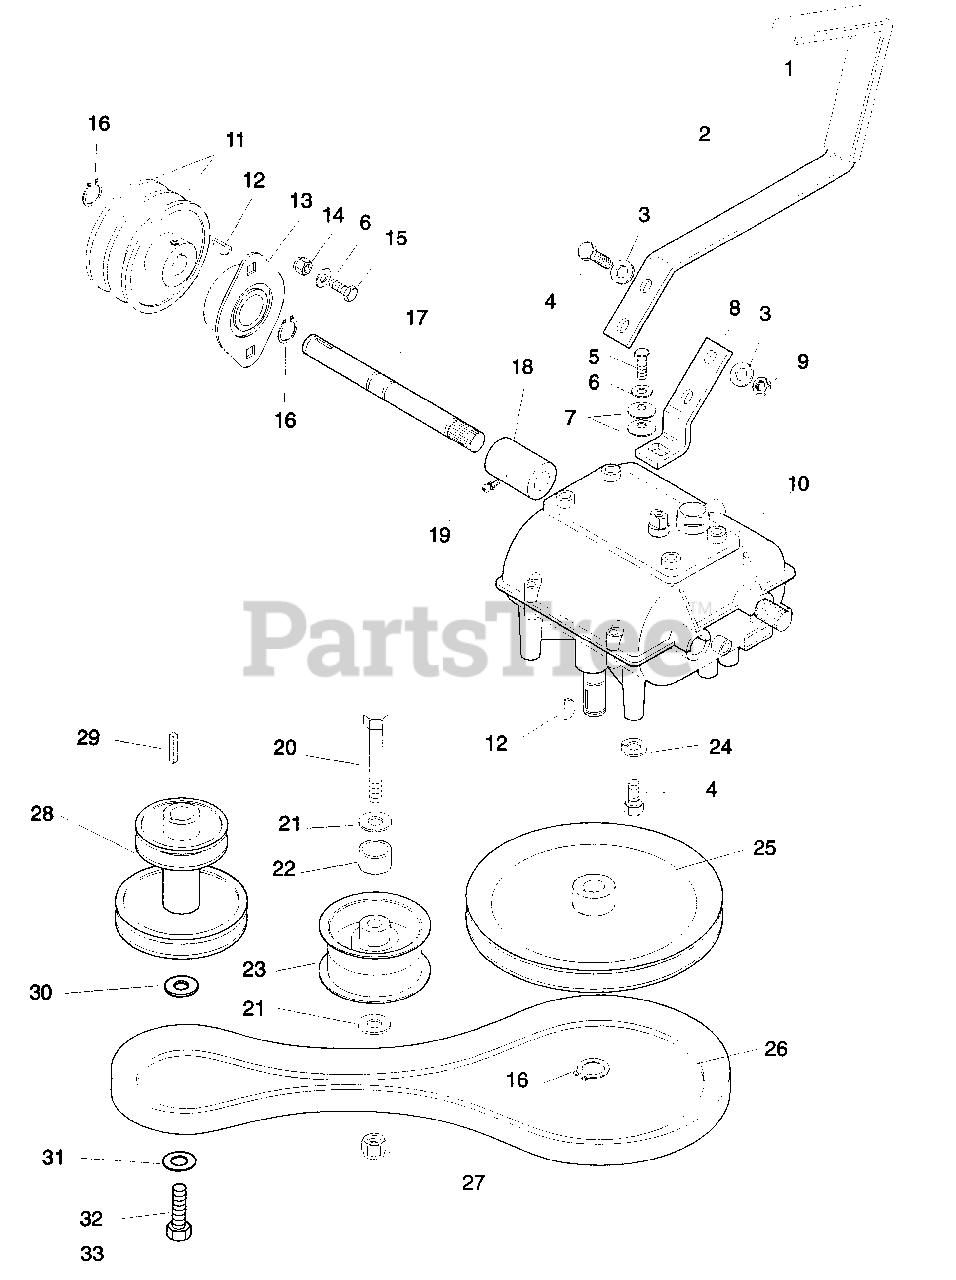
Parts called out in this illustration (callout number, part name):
1	Grip
2	Lever, Transmission Shift
3	Washer-Flat-Steel .344 x .688 x .065
4	Bolt-Hex .31-18 x 1.00 Grade 5
5	Bolt-Hex .25-28 x .75 Grade 5
6	Washer-Flat-Steel .281 x .62 x .065
7	Washer, Belleville
8	Arm, Transmission Shift
9	Nut-Locking-Center .31-18
10	Transmission, 5-Speed Pro 32
11	Drive Sheave (Upper) - Pro-100
12	Key, Woodruff .19 x .75
13	Bearing-Flange .625 x 1.875 x .797
14	Nut-Locking-Center .25 -20
15	Bolt-Hex .25-20 x .75 Grade 5
16	Ring-Retaining-External .579 x .93
17	Half Shaft, Transmission, Pro-150
18	Coupler, Transmission Shaft
19	Fitting-Lube .25-28 x .256
20	Bolt-Hex .38-16 x 2.25 Grade 5
21	Washer-Flat-Steel .406 x .812 x .065
22	Spacer, .625 x .385 x .55
23	Idler-Pulley Flat 3.25 x .625
24	Washer-Locking .31 x .078
25	Pulley-V 7.50 x .63
26	V-Belt A-Section 14.9 x 33/64
27	Nut-Locking-Center .38-16
28	Crank Sheave-Pro 1
29	Key-Square .248 X 2.38
30	Washer-Locking .44
31	Washer-Special .42 X 2.000 X 2.50
32	Bolt-Hex M10 X 1.5 X 60 (075, 077)
33	Bolt-Hex .44-20 X 2.250 (078, 079)
